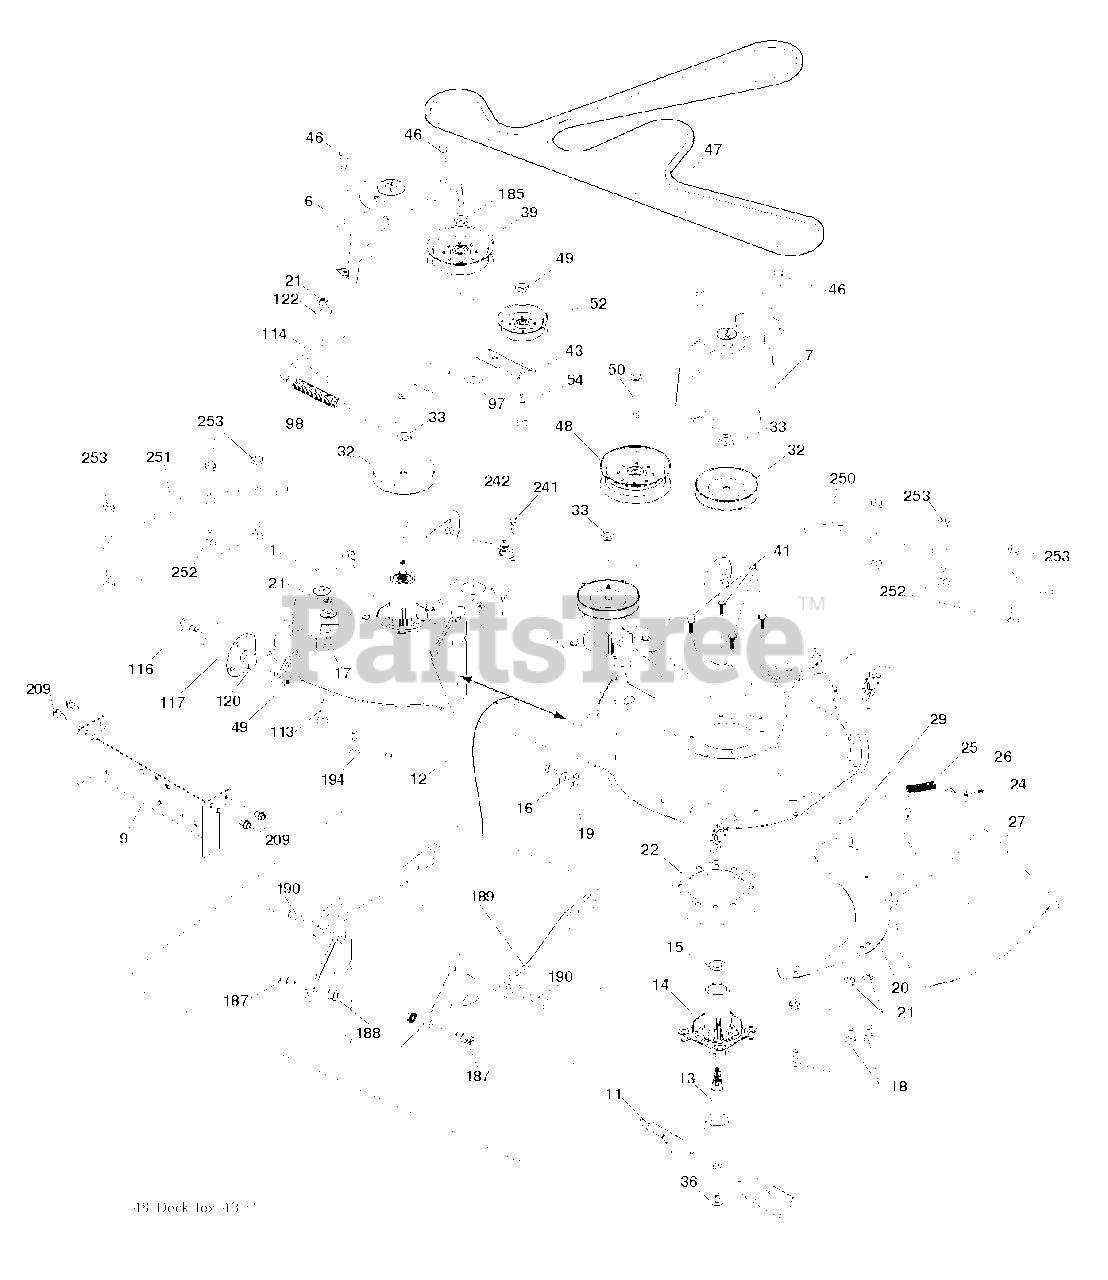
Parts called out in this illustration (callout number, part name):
1	DECK.WLDMT.W/TUBES.48".OR.RP
6	COVER.MANDREL.LH.48"(2 2)
7	COVER.RH.MANDREL
9	TORQUE.STRAP.PNT.BLACK
11	48" HI-LIFT BLADE
12	ROD.ANTI.SWAY.48/54"K4
13	SHAFT ASM MANDREL
14	HOUSING.MANDREL.4PT.
16	WASHER
17	BOLT
18	BOLT
19	PIN.COTTER.5/16.BOW TI
20	BAFFLE, VORTEX MWR
21	LOCKNUT
22	STRIPPER.MANDREL.ROUND.BLACK
24	CAP-SLEEVE LT
25	SPRING, TORSION
26	NUT PUSH M
27	DEFLECTOR SUBS TO 532 180655
29	ROD.HINGE
32	PULLEY MANDREL
33	NUT.FLANGE.LOCK.TOP
36	SCREW.SEMS.7/16-20X1.HEX.HEAD
39	RB PULLEY.IDLER.4.50/HUB SPEC
41	BOLT.HEX.WASHR.HED.313-18X1.19
46	SCREW.1/4-20X5/8
47	BELT.DRIVE.DECK
48	PULLEY.IDLER.2006
49	NUT LOCK FLG 3/8-16 UNC
50	SCREW TT 3/8-16X2-1/4 UNC
52	PULLEY.IDLER.48"PRIMARY
54	BOLT.3/8-16X1.50
98	SPRING, DECK DRIVE
114	ROD.TENSION.RELIEF.TEX (2 2)
116	BOLT.SHOULDER.3/8-16X3-5/8.
117	WHEEL. GUAGE RALLY
120	WASHER
122	BUSHING.RELIEF.TENSION
185	NUT.LOCK.FLANGE.7/16
187	STUD.FASTNER.W/ANTI-ROTATE
188	NUT LOCK HEX FLANGE 5/16-18
189	ARM.SUSPENSION.MOWER
190	BOLT.SHOULDER
194	BOLT.HEX.WASHER.HEAD.7/16-24X
209	SCREW
241	SCREW.TT.#10-32X.5.3/8.FLANGE
242	PORT.WASHOUT
250	PLATE.REIN.FRNT.BOLTON.48X431
251	PLATE.REIN.SIDE.BOLT.ON.48X431
252	RHSNB, 1/4-20 X 1, GR5
253	NUT T
